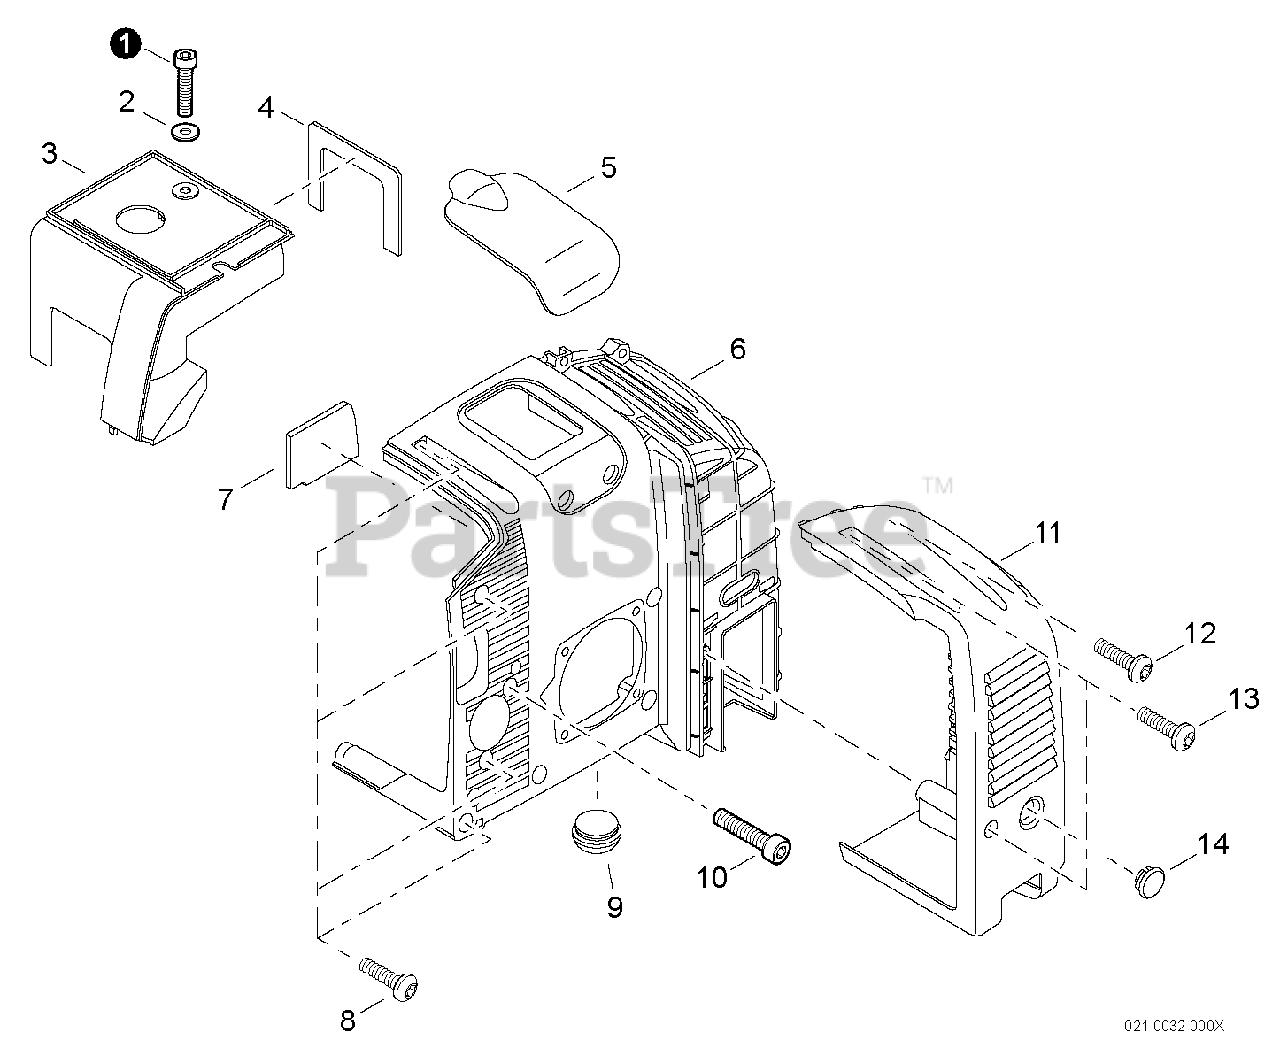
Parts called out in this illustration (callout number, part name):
1	SCREW - 5X20
2	WASHER - 5
3	SHIELD, CYLINDER
4	PLATE, INSULATOR
5	COVER, SPARK PLUG
6	COVER, ENGINE
7	PLATE, INSULATOR
8	SCREW - 5X20
9	CUSHION
10	SCREW - 5X16
11	COVER, MUFFLER
12	SCREW - 5X25
13	SCREW - 5X16
